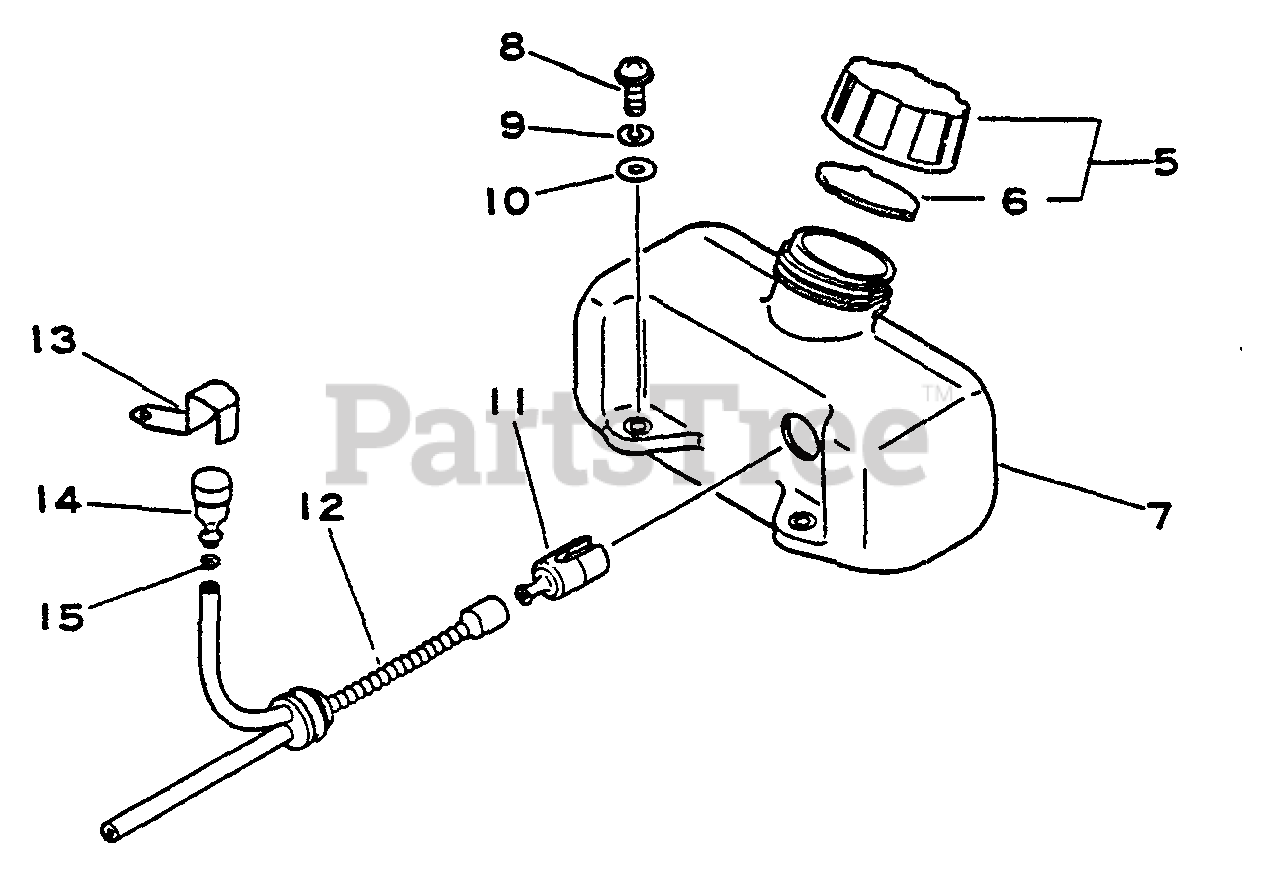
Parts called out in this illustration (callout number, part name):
5	CAP ASSY
6	GASKET
7	TANK, FUEL
8	SCREW 5×16
9	WASHER, SPRING 5
10	WASHER 5.5×12×0.8
11	FILTER, FUEL
12	PIPE, FUEL
14	VENT ASSY
